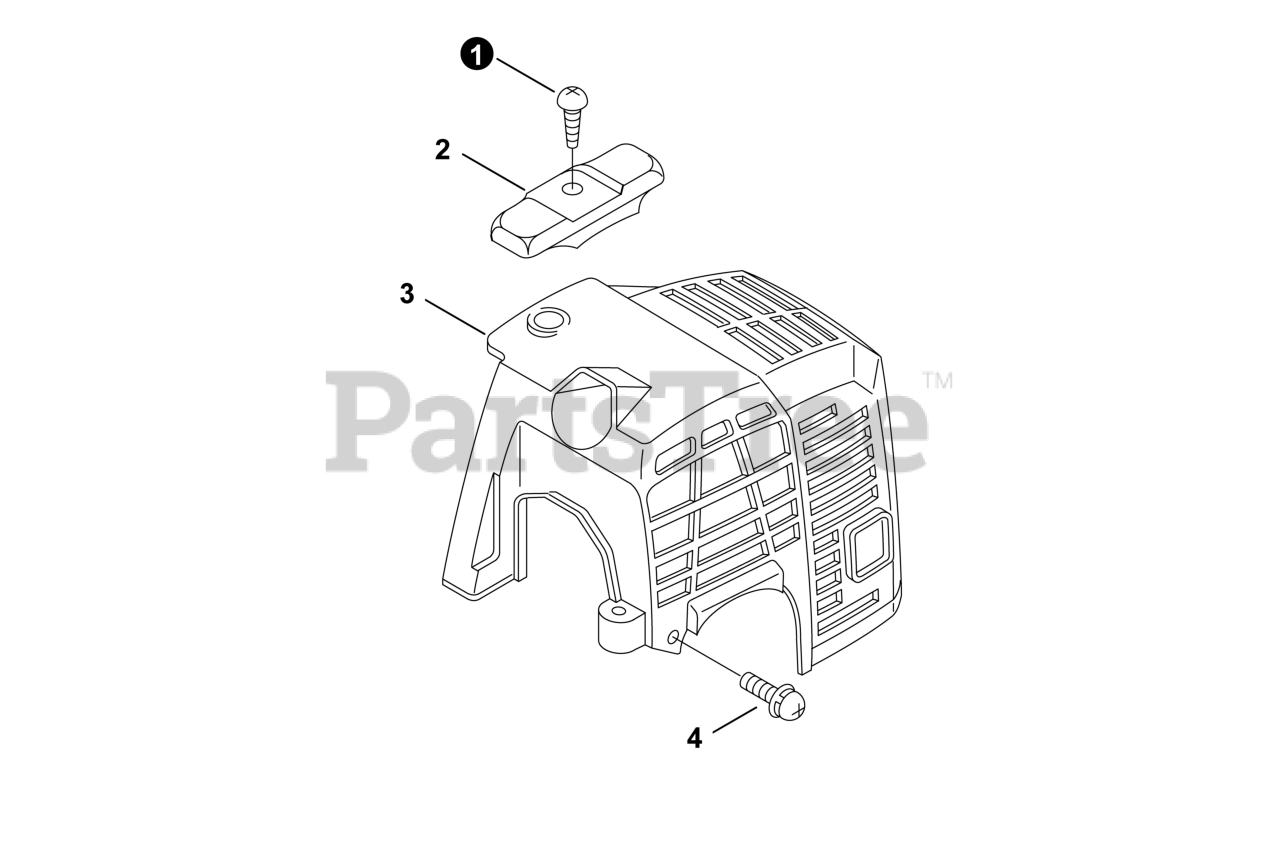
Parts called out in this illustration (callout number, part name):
1	SCREW, TAPPING 5x20
2	GUARD, TOP
3	COVER, ENGINE
4	SCREW 4x16
